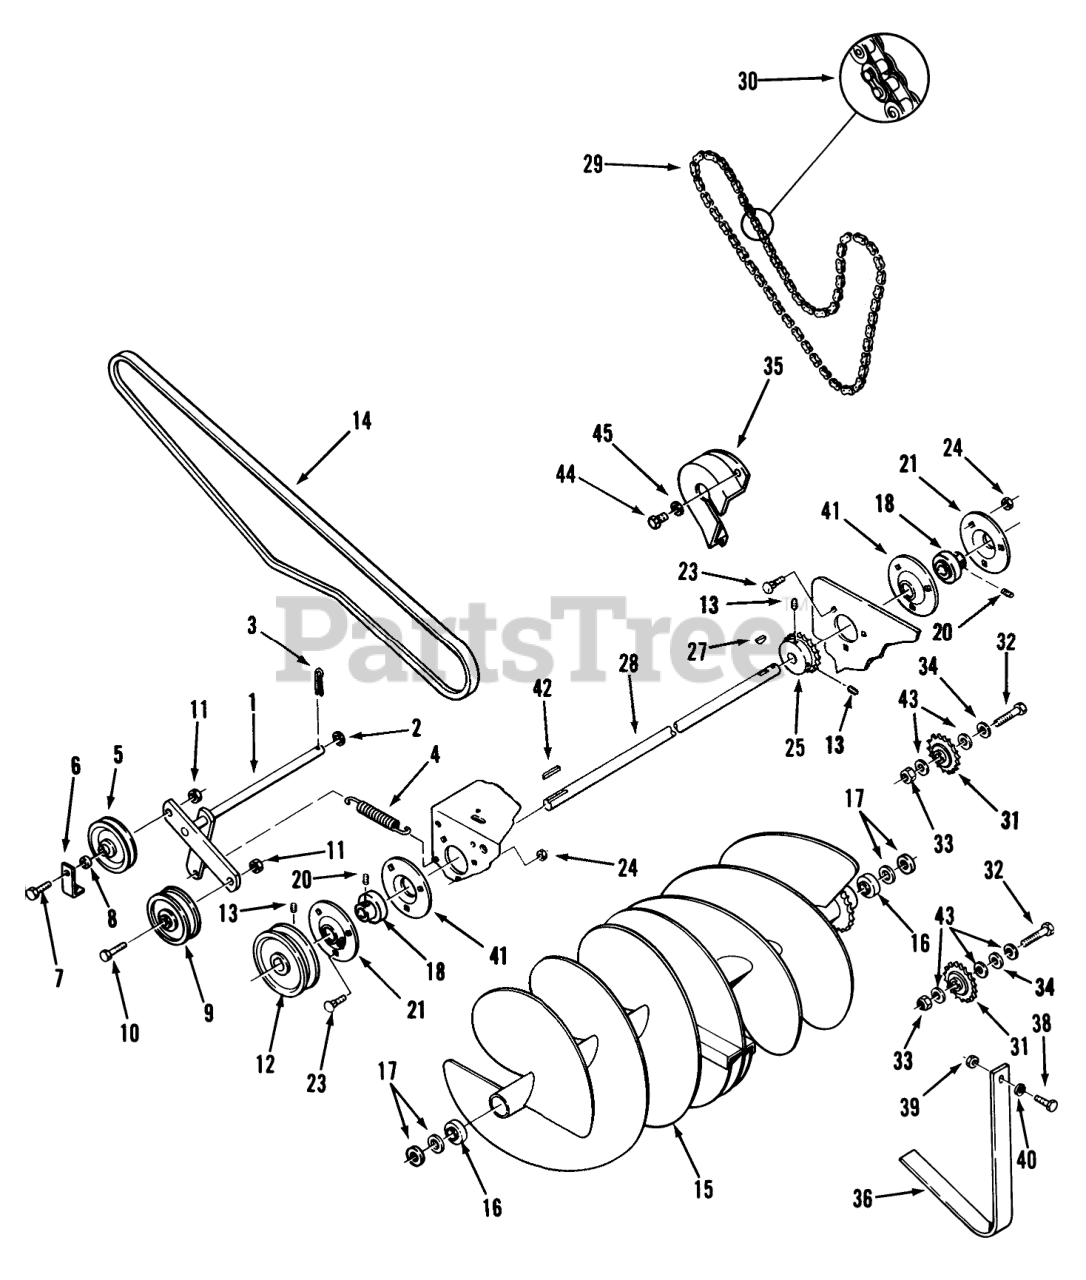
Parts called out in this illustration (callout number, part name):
1	ASSY IDLER ARM R
2	Washer
3	Cotter Pin
4	SPRING R
5	PULLEY-IDLER
6	Spacer
7	Bolt
8	SPACER
9	Idler Pulley
10	BOLT
11	Nut
12	PULLEY
13	Set Screw
14	V-BELT
15	Auger
16	BEARING-BALL
17	Washer
18	BEARING AND COLLAR
20	SET SCREW
21	FLANGE-ZERK RELUBE
23	Bolt
24	Nut
25	Sprocket 14T x 40
27	KEY-WOODRUFF
28	Shaft
29	CHAIN
30	MASTER LINK CHAIN
31	Idler Sprocket
32	Bolt 1/2-13 X 2
33	Eslok Nut
34	SPACER
35	GUARD-CHAIN
36	Guard
38	H H C S
39	Nut 1/4-20
40	WASHER
41	Flange
42	KEY-STRAIGHT
44	Bolt
